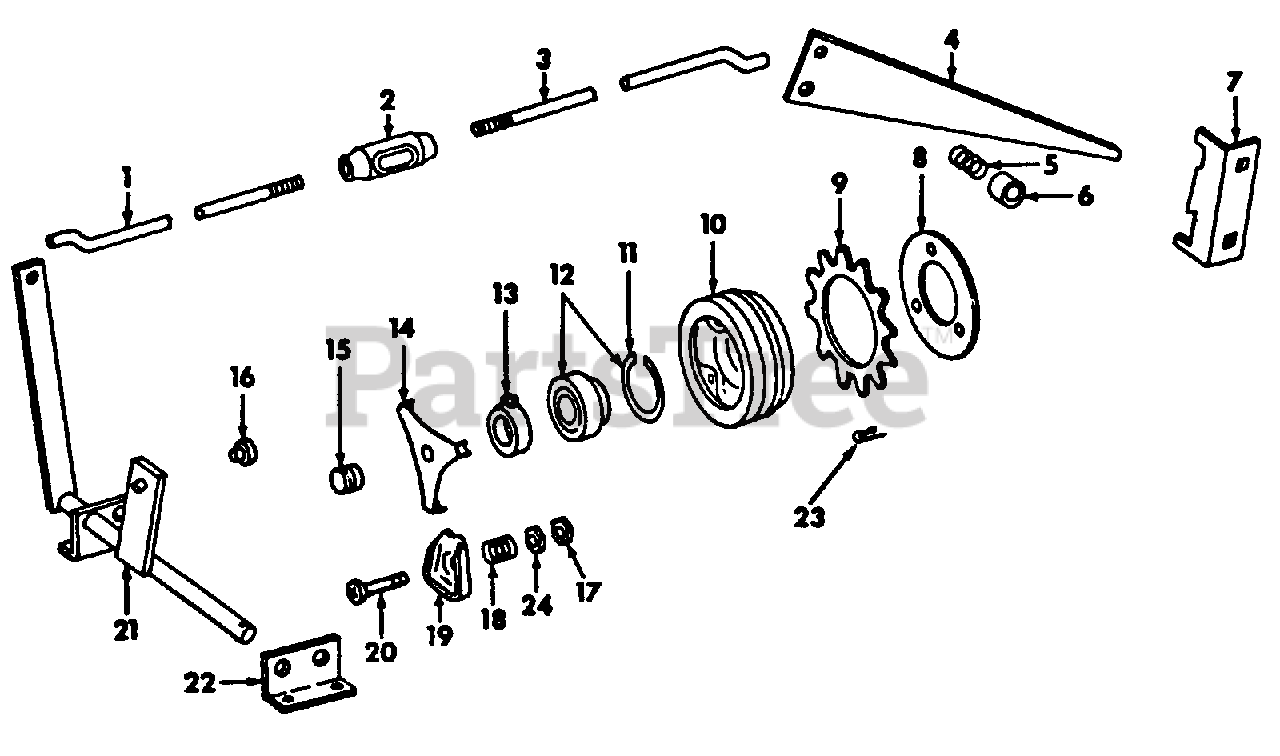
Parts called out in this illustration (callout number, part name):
1	Rod, Clutch
2	Turnbuckle, Rod
3	Rod, Rear Clutch
4	Lever, Handle
5	Spring, 15 Ga Compression
6	Spacer, Spring
7	Latch, Handle
8	Plate, Pressure
10	Pulley, Mower Actuating -Replaces 473 474 R1
11	Ring, Bearing Snap
12	Bearing w/Snap Ring, Ball
13	Collar w/Set Screw & Lock Nut, Brg
15	Button, Thrust
16	Button, Wear
17	Nut, 1/4-28 Hex Jam
18	Spring, Compression
19	Lever, Throw-Out
20	Screw, Special Machine
21	Shaft w/Button 473 483 R1, Clutch
22	Bracket, Pivot
23	Spring, Friction Disc
24	Nut, 1/4-28 Hex
